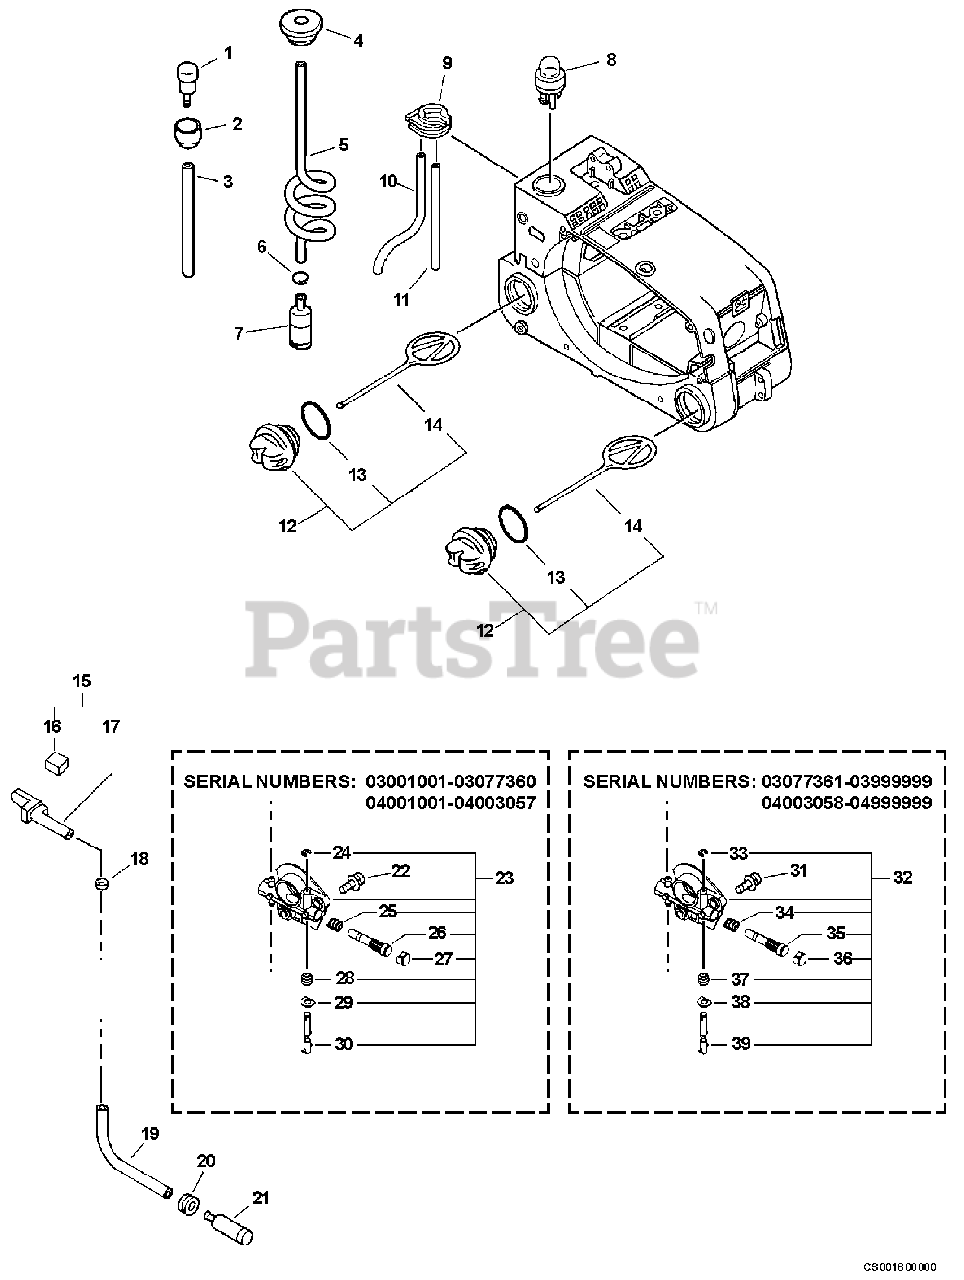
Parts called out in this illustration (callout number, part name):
1	VENT, FUEL TANK
2	HOLDER, VENT
3	PIPE - 3X5X150 -- BLACK
4	GROMMET
5	PIPE, FUEL - SPIRAL
6	CLIP - 6.5
7	FILTER, FUEL
8	PUMP, PURGE
10	PIPE - 2X4X42 -- CLEAR
11	PIPE - 3X5X70 -- BLACK
12	CAP ASSY - ORANGE
13	O-RING - 25
14	CONNECTOR, CAP
15	OIL PIPE KIT
16	PAD, FOAM
17	PIPE - OIL
18	CLIP - 6.5
19	PIPE - 3X6X115 -- BLACK
20	GROMMET
21	FILTER, OIL
22	SCREW - 5X12
23	AUTO-OILER ASSY
24	RING, RETAINING
25	SPRING, PLUNGER
26	PLUNGER ASSY
27	CAP, OIL PUMP
30	NEEDLE, ADJUST
31	SCREW - 5X12
32	AUTO-OILER ASSY
33	RING, RETAINING
35	PLUNGER
36	CAP, OIL PUMP
39	NEEDLE, ADJUST
